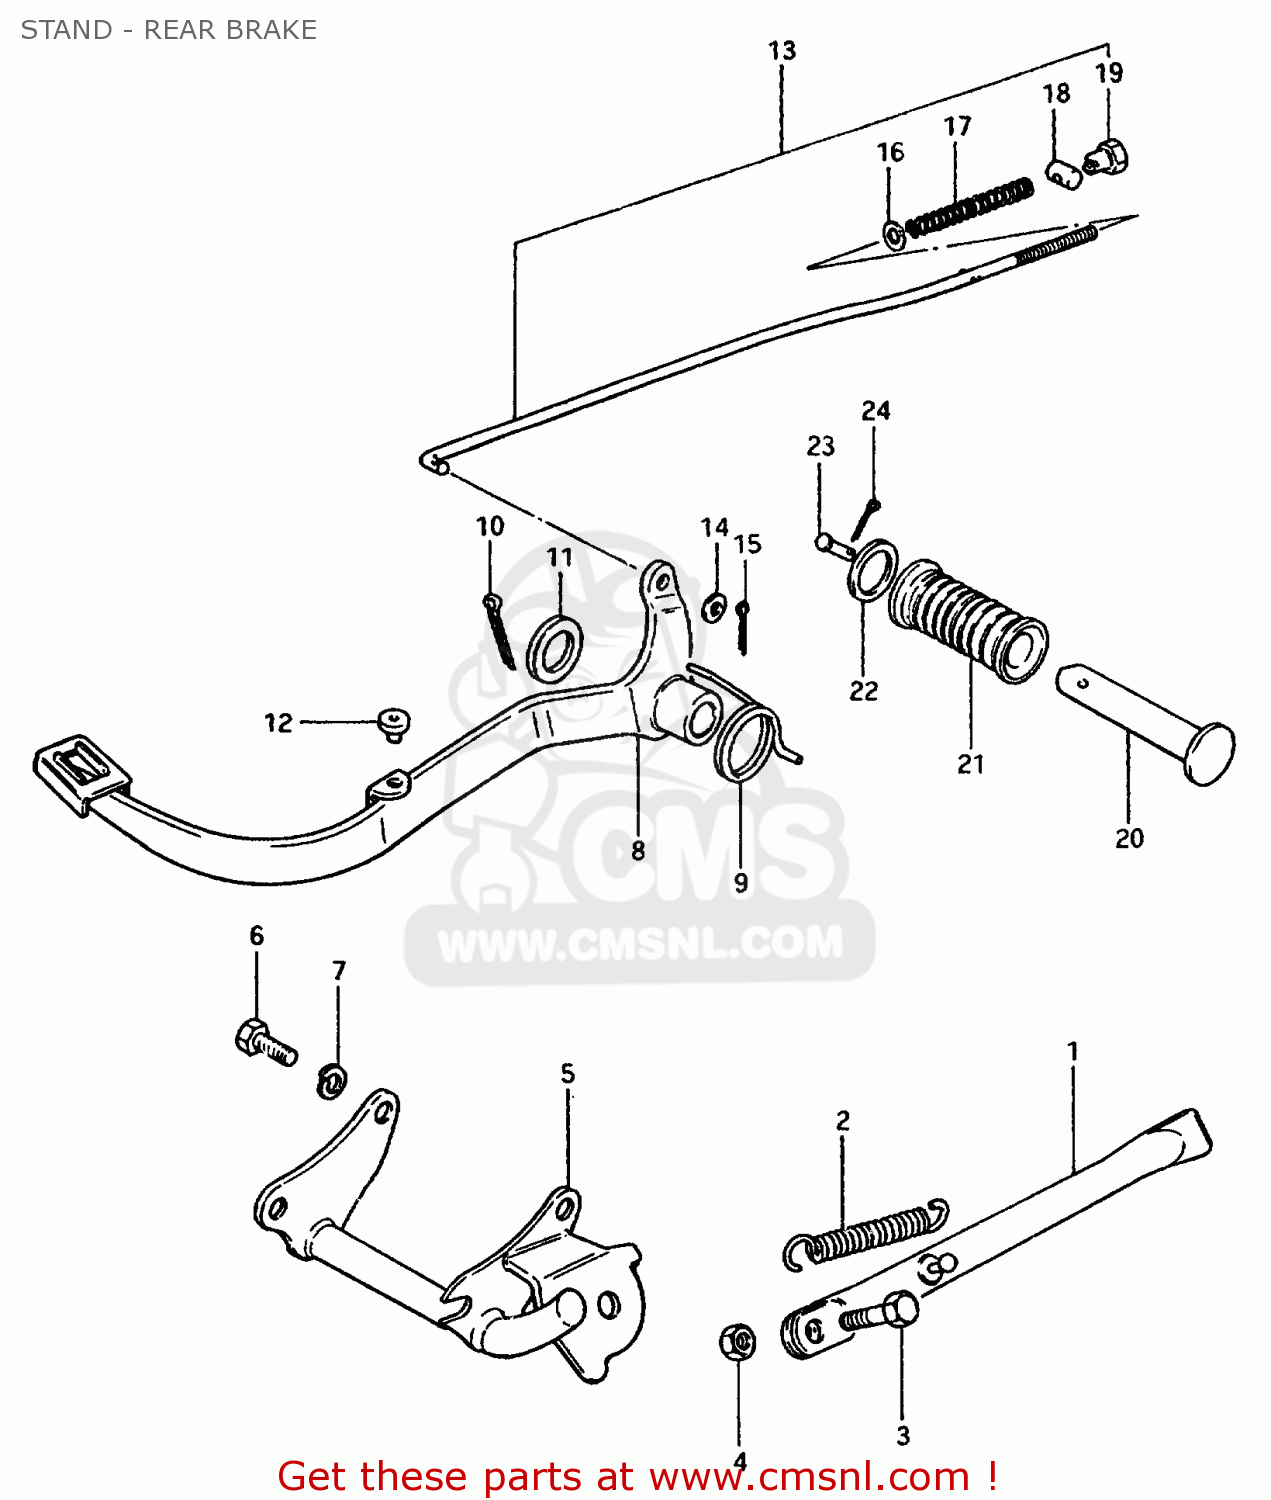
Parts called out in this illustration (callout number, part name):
1	STAND,SIDE
2	SPRING
3	BOLT
4	NUT
5	BAR, FRONT FOOTREST
6	BOLT
7	LOCK WASHER
8	PEDAL, BRAKE
9	SPRING
10	COTTER PIN
11	WASHER(15.5X26X2.3)
12	STOPPER,BRAKE PEDAL
13	ROD ASSY, REAR BRAKE
14	WASHER
15	PIN 20X20
16	WASHER
17	SPRING
18	PIN(11X18)
19	NUT
20	BAR,FOOTREST RUBBER
21	RUBBER,PILLION FOOTREST
22	WASHER (19.5X32X2)
23	PIN
24	PIN 20X20
